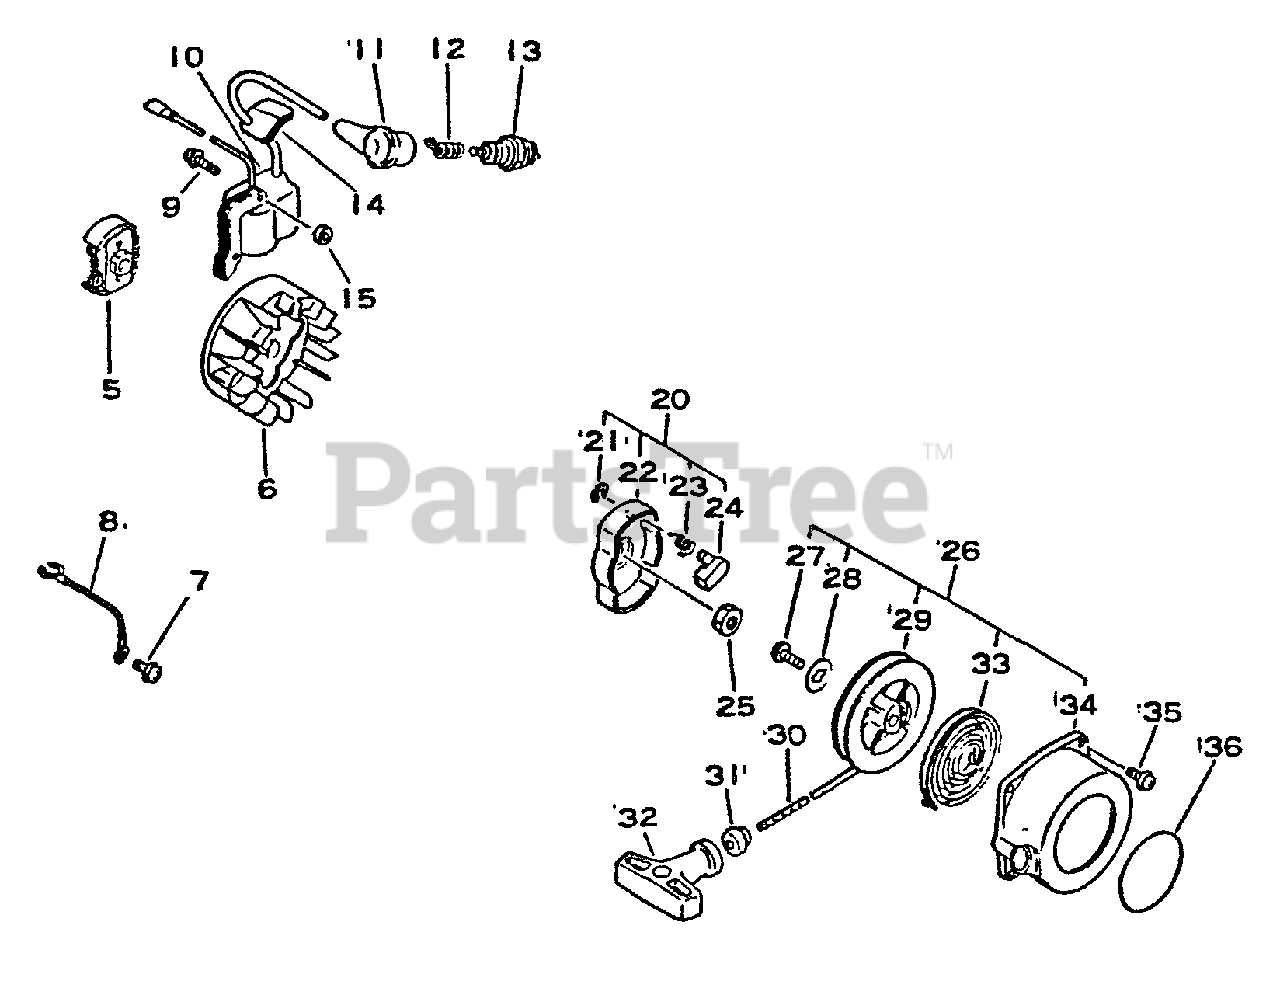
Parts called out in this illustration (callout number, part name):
5	CLUTCH ASSY
6	FLYWHEEL
7	SCREW 5×10
8	LEAD - GROUND
9	SCREW 4×22
10	COIL, IGNITION
11	CAP, SPARK PLUG
12	TERMINAL, SPARK PLUG
13	SPARK PLUG - BPM7A
13	SPARK PLUG - BPMR7A
20	STARTER PAWL ASSY
21	RING, RETAINING - 6
22	CATCHER, PAWL
23	SPRING, RETURN
24	PAWL, STARTER
25	NUT 8×1.25
26	STARTER ASSY
28	WASHER
29	REEL, ROPE
30	ROPE, STARTER
31	GUIDE, ROPE
32	GRIP, STARTER
33	SPRING, RECOIL
34	CASE, RECOIL STARTER
35	SCREW 4×16
36	LABEL - ECHO
